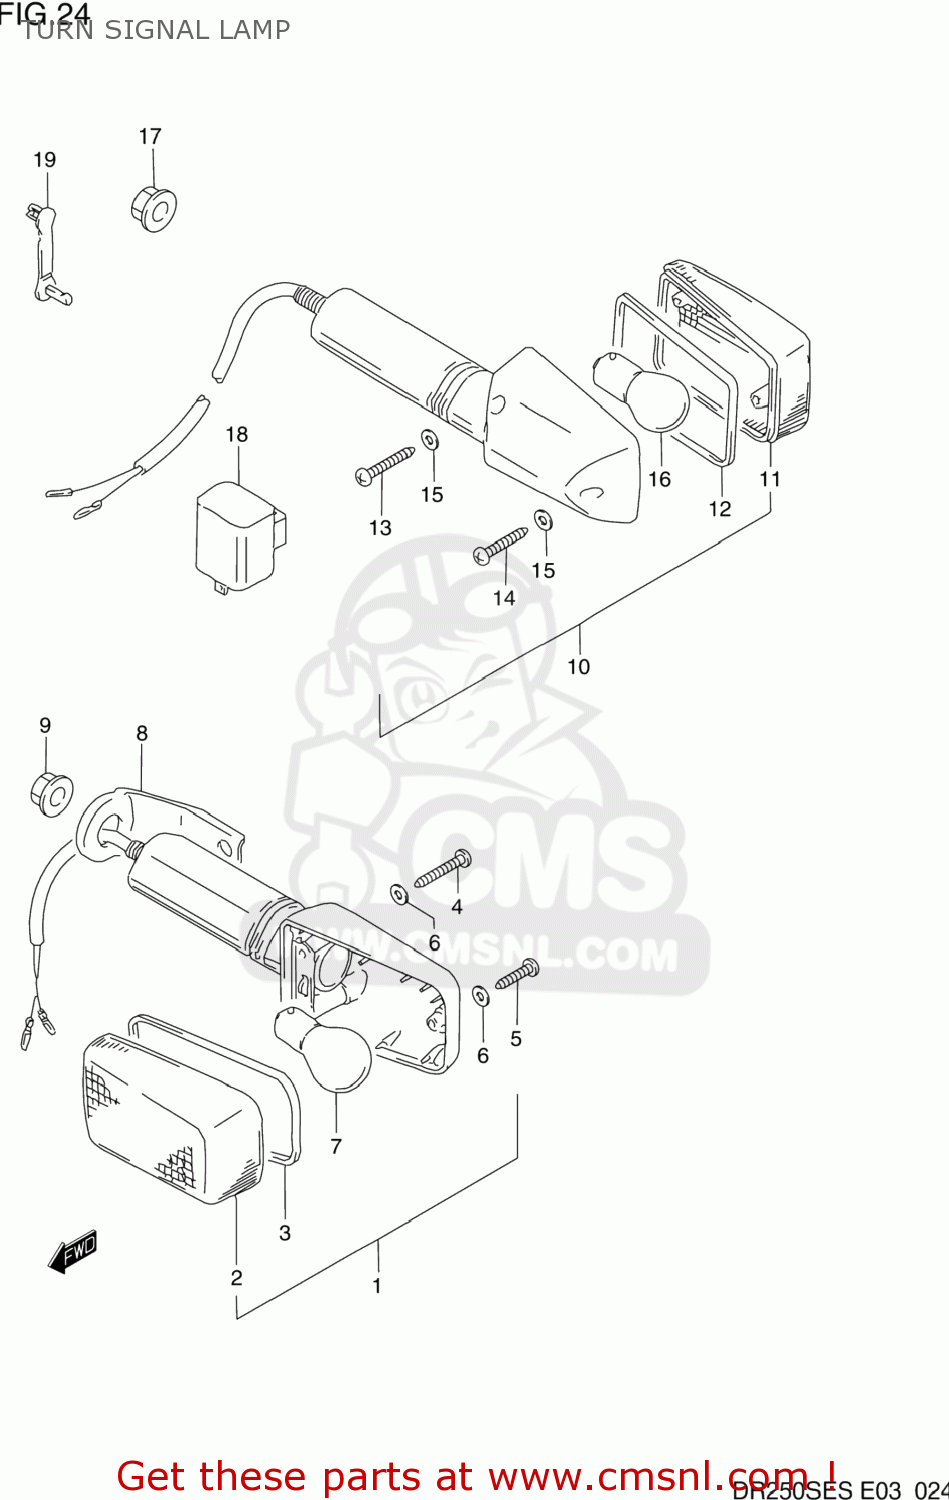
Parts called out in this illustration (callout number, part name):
1	LAMP ASSY,FR TURN SIGNAL
2	LENS
3	GASKET (NAS)
4	SCREW(3X30)
5	SCREW
6	GASKET (NAS)
7	BULB(12V21W)
8	BRACKET,FR TURNSIGNAL,R
9	NUT
10	LAMP ASSY,RR TURNSIGNAL
11	LENS
12	GASKET (NAS)
13	SCREW(3X30)
14	SCREW
15	GASKET (NAS)
16	BULB(12V21W)
17	NUT
18	RELAY ASSY,TURNSIGNAL
19	CLAMP(L:33)
